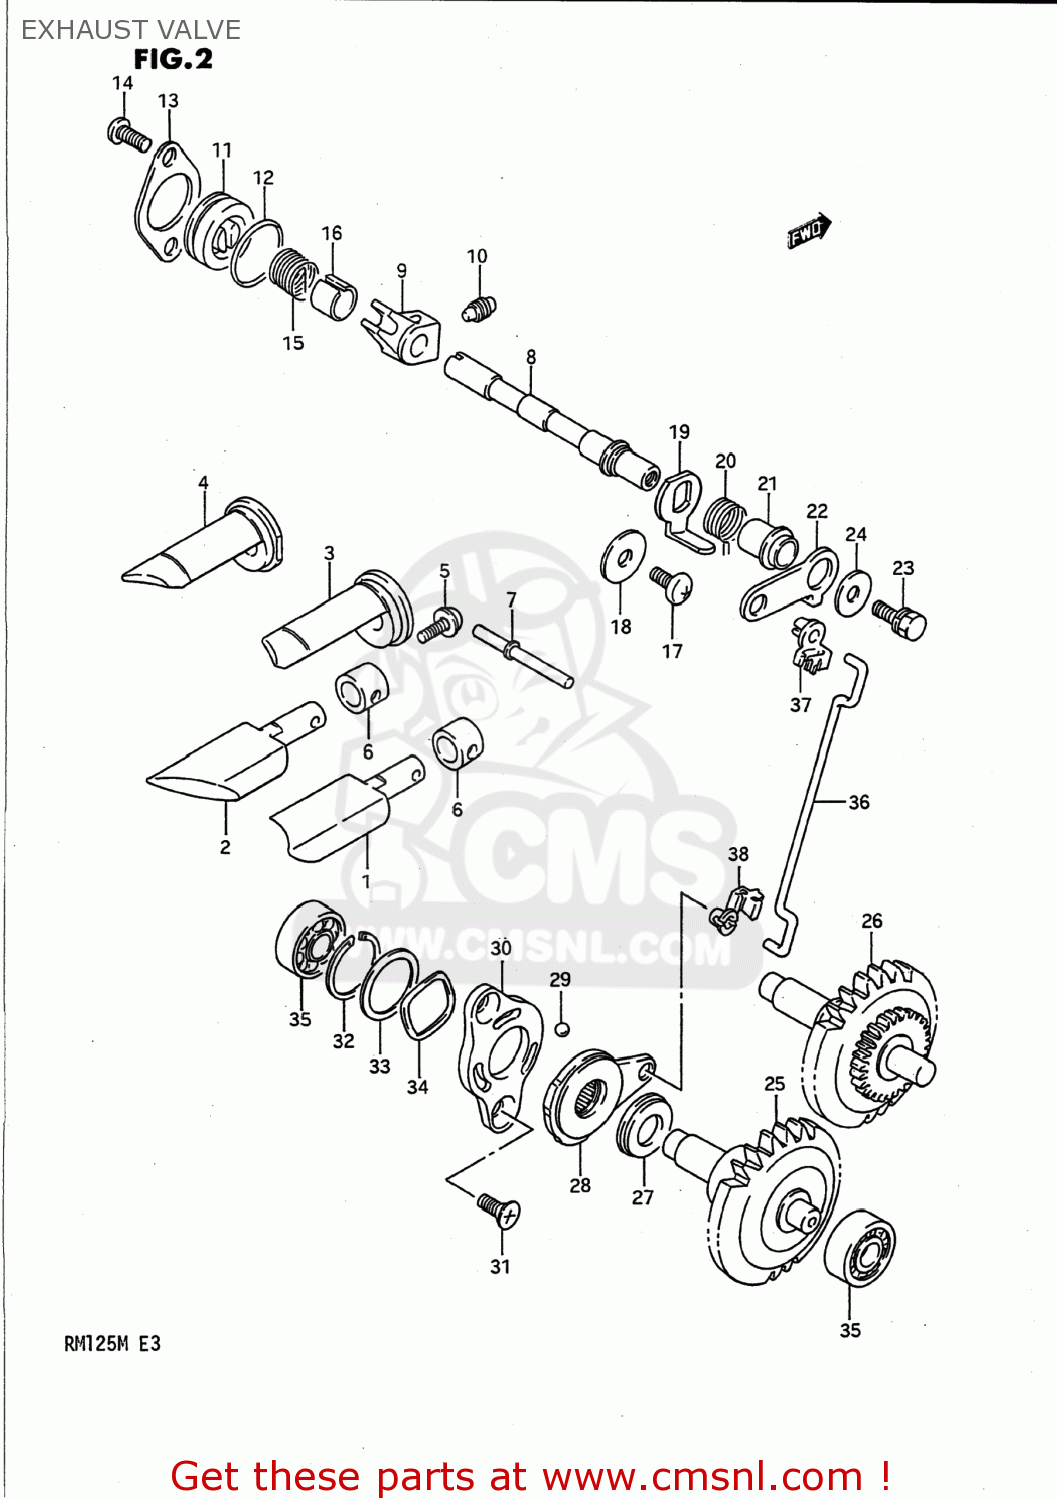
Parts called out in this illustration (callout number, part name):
1	VALVE,EXHAUST,R
2	VALVE,EXHAUST,L
3	GUIDE,EXHAUST VALVE,R
4	GUIDE,EXHAUST VALVE,L
5	SCREW
6	HOLDER,EXHAUST VALVE
7	PIN,EXHAUST VALVE 48.5MM
8	SHAFT,EXHAUST VALVE
9	ARM,EXHAUST VALVE SHAFT
10	SCREW
11	CAP,EXHAUST VALVE
12	O RING(D:1.9,ID:22.6)
13	RETAINER,EXHAUST VALVE
14	SCREW
15	SPRING
16	SPACER,EXHAUST VALVE SPRING
17	BOLT
18	WASHER
19	LEVER,EXHAUST VALVE NO
20	SPRING
21	SPACER,EXHAUST VALVE
22	LEVER,EXHAUST VALVE NO
23	BOLT
24	WASHER (5.5X16X1.2)
25	GOVERNOR ASSEMBLY,EXHAUST
26	GOVERNOR ASSY,EXHAUST VALVE
27	BEARING(10X22X2.8)
28	ACTUATOR,EXHAUST VALVE
29	BALL
30	STARTER,EXHAUST VALVE ACTUATOR
31	SCREW(5X10)
32	CIRCLIP
33	SHIM(19.1X25X0.3)
34	WASHER
35	BEARING(8X22X7)
36	ROD,EXHAUST VALVE
37	BUSH,EXHAUST VALVE ROD NO.1
38	BUSH,EXHAUST VALVE ROD NO.2
